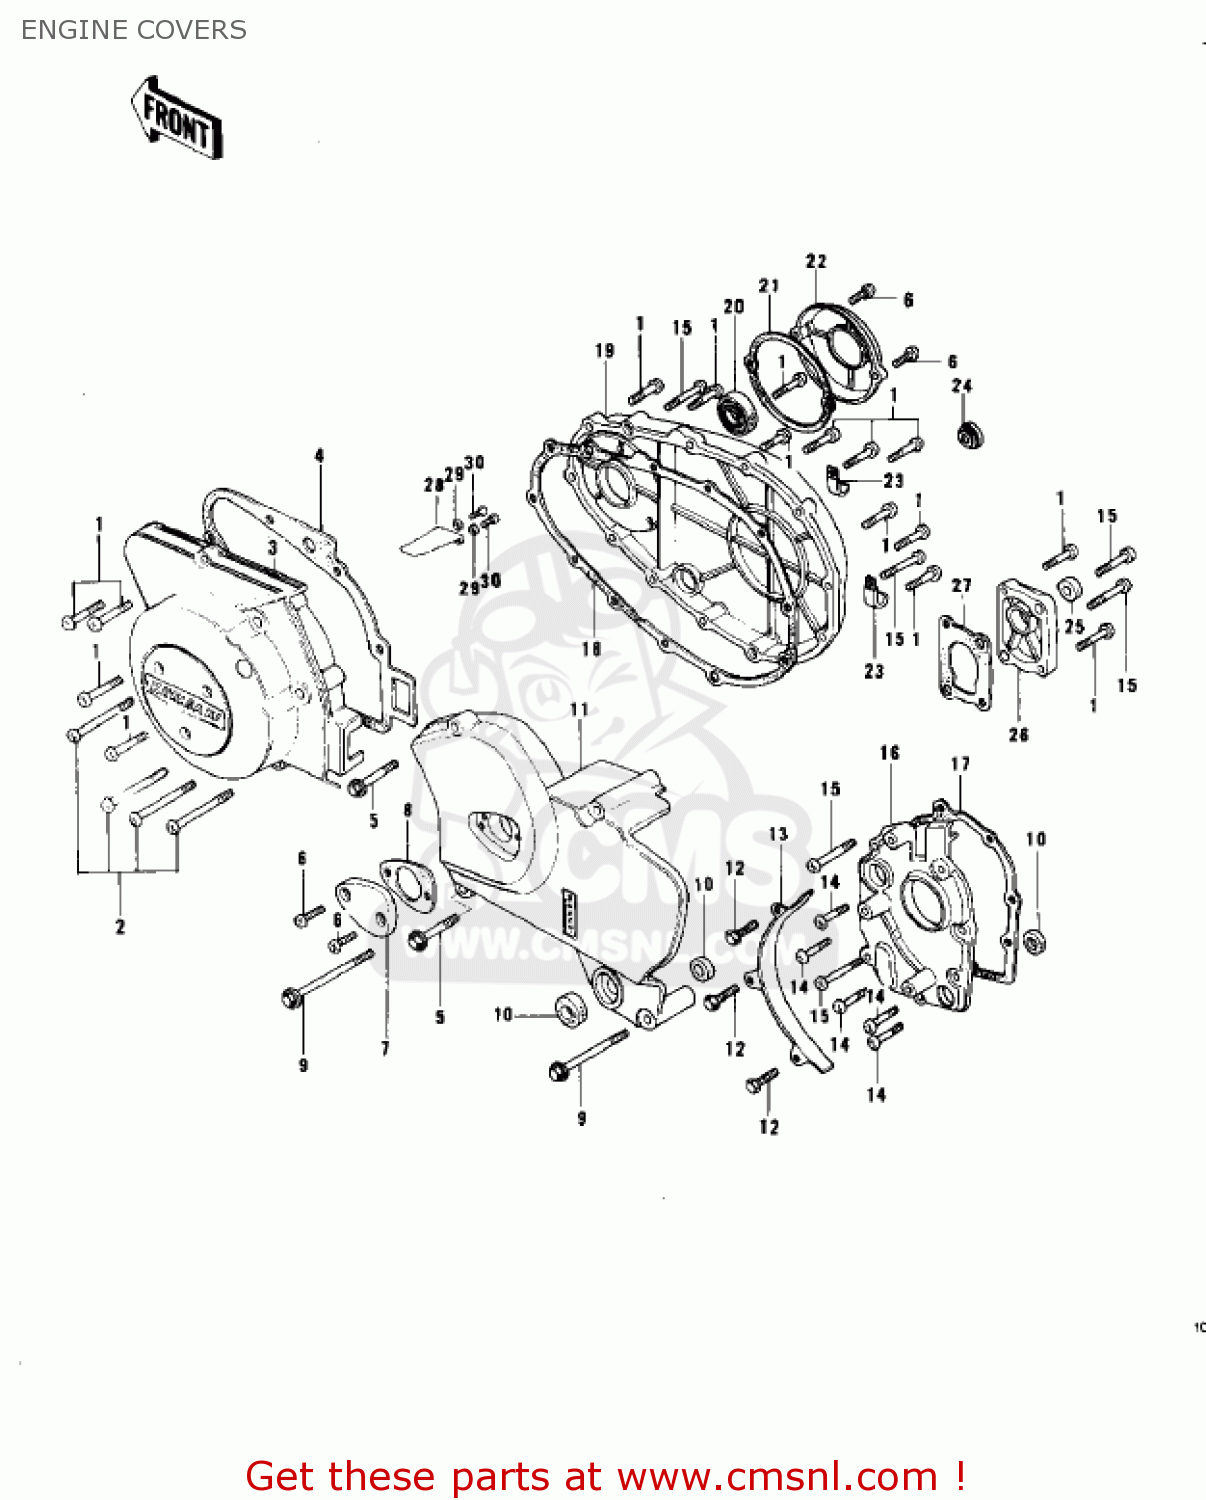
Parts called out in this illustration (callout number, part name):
1	SCREW-PAN HEAD,6X30
2	SCREW-PAN HEAD,6X60
3	COVER,GENERATOR
4	GASKET,GENERATOR COVE (MCA)
5	BOLT,HEX HEAD,6X34
6	SCREW-PAN HEAD,6X18
7	CAP,CLUTCH ADJUST
8	GASKET,CLUTCH ADJUST (MCA)
9	BOLT-FLANGED,6X95
10	OIL SEAL,TB13225.5
11	COVER,ENGINE SPROCKET
12	BOLT-UPSET 6X14
13	GUIDE-CHAIN
14	SCREW-PAN HEAD,6X22
15	SCREW-PAN HEAD,6X40
16	COVER,MISSION
17	GASKET,TRANSMISSION C (NAS)
18	GASKET,R.H ENGINE COV (MCA)
19	COVER,R.H ENGINE
20	OIL SEAL,R.H CRNKSFT
21	GASKET,BREAKER COVER (MCA)
22	CAP
23	CLAMP,WIRING HARNESS
24	GAUGE,OIL LEVEL
25	OIL SEAL,SC22325
26	COVER,KICK
27	GASKET,KICK COVER (MCA)
28	CLAMP,GENERATOR LEAD
29	WASHER-SPRING,5MM
30	SCREW-PAN-CROS
